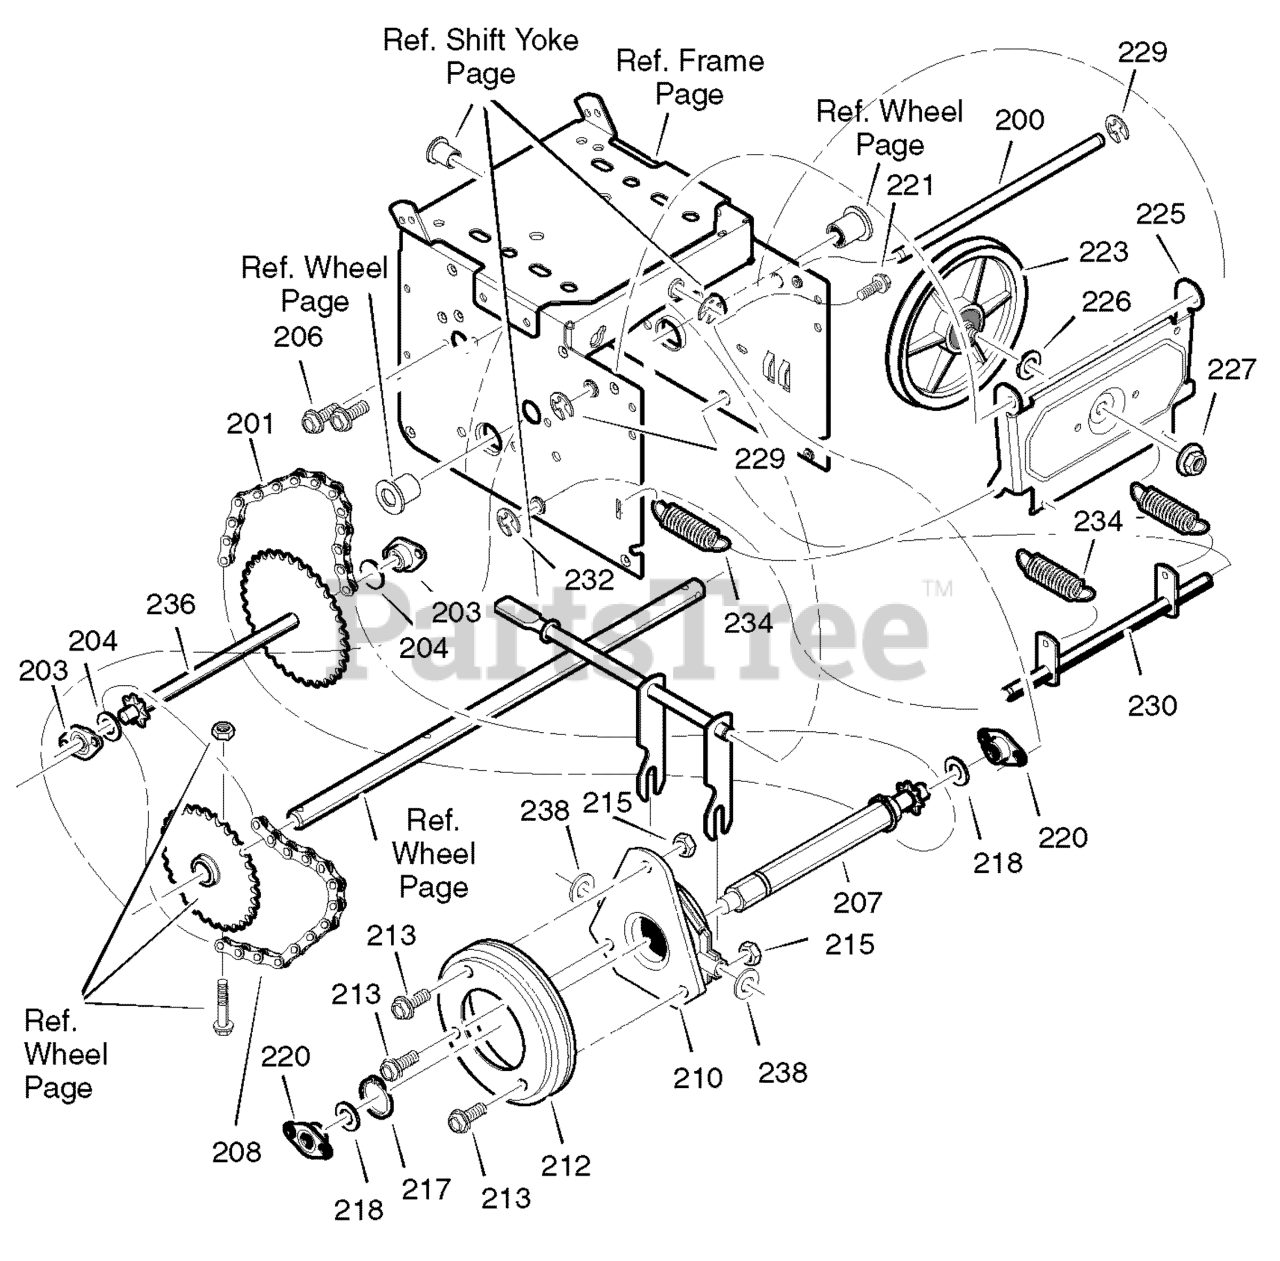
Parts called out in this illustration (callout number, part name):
200	LF AXLE, SWING PLATE YZ
201	CHAIN, ROLLER #42x19.00
203	BEARING AND RETAINER, ASSY
204	WASHER
206	SCREW, TAP 5/16-18 x 0.5
207	ASSY, HEX SHAFT
208	CHAIN, ROLLER #36x18.00 LG
210	BEARING, TRUNION CLUTCH R
212	WHEEL, FRICTION DISC
213	SCREW, 1/4-20 x 0.63
215	NUT, KEPS HEX 1/4-20
217	RING, RETEXT
218	WASHER
220	BEARING AND RETAINER, ASSY
221	SCREW, TAP 5/16-18 x .5
223	ASSY, FRICTION PULLEY
225	LF PLATE, SWINGING YZ
226	SPACER, FRICTION PULLEY
227	NUT, FLANGE LOCK 3/8-24
229	RETAINER, RING
230	LF ASSY, SPRING LINK YZ
232	RETAINER, RING
234	SPRING, EXTENSION
236	WLD, INTERMED SPROCKET 33T/7
238	WASHER, FLAT
